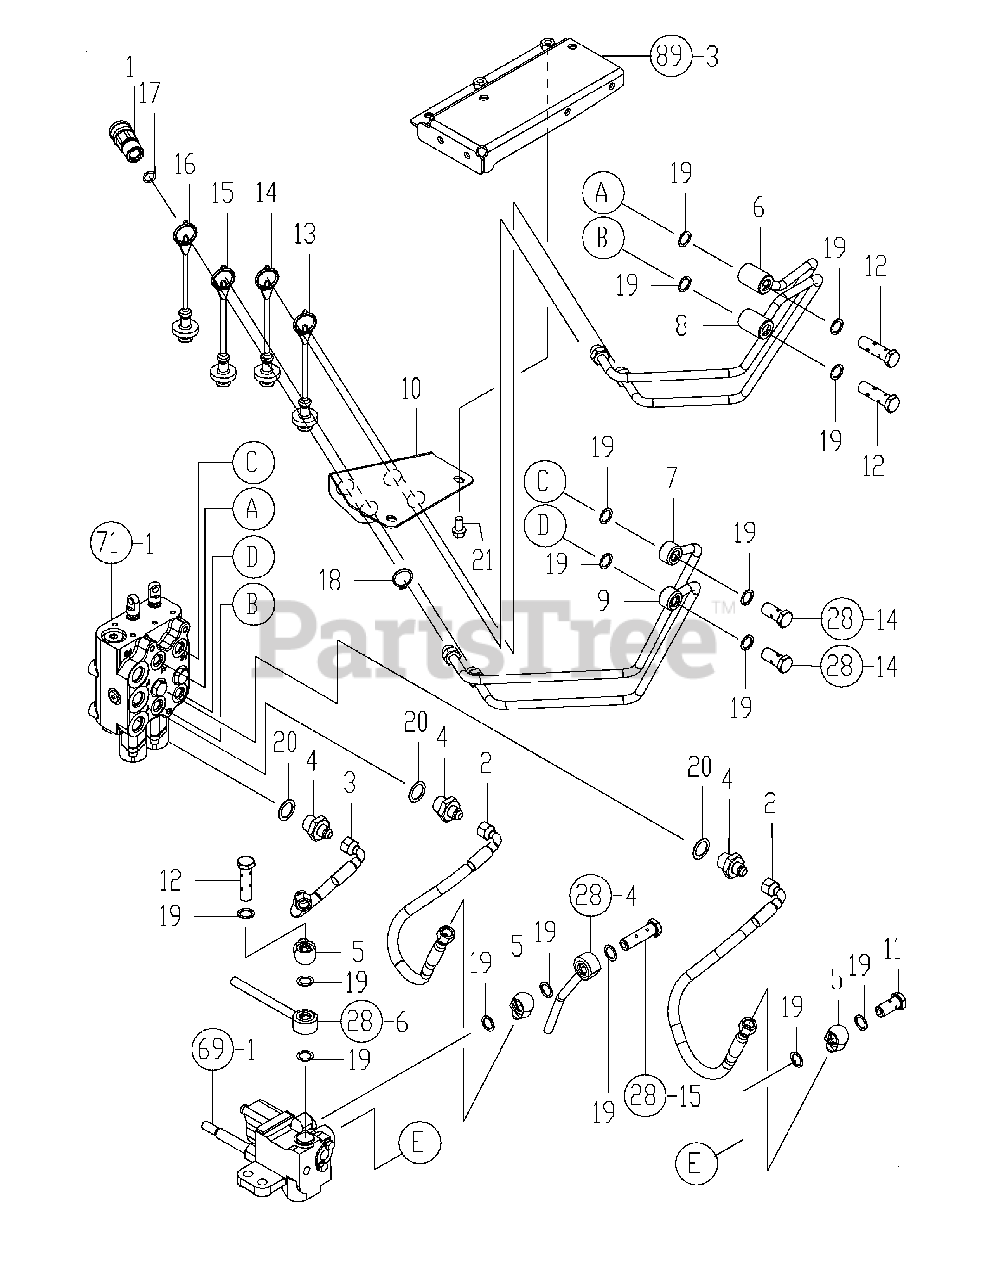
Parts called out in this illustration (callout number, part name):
1	COUPLER, HYD.QUICK
4	JOINT3/4UNF-9/16UNF
5	JOINT9/16UNF-14.5
6	HP PIPE CMP, SCV A1
7	HP PIPE CMP, SCV A2
8	HP PIPE CMP, SCV B1
9	HP PIPE CMP,S CV B2
10	STAY(SCV COUPLER)
11	BALL JOINT BOLT 9/16
12	BALL JOINT BT L 9/16
14	PLUG,DUST BLUE
15	PLUG,DUST YELLOW
16	PLUG,DUST GREEN
19	GASKET, 14 X 1.0
20	GASKET, 19 X 1.0
